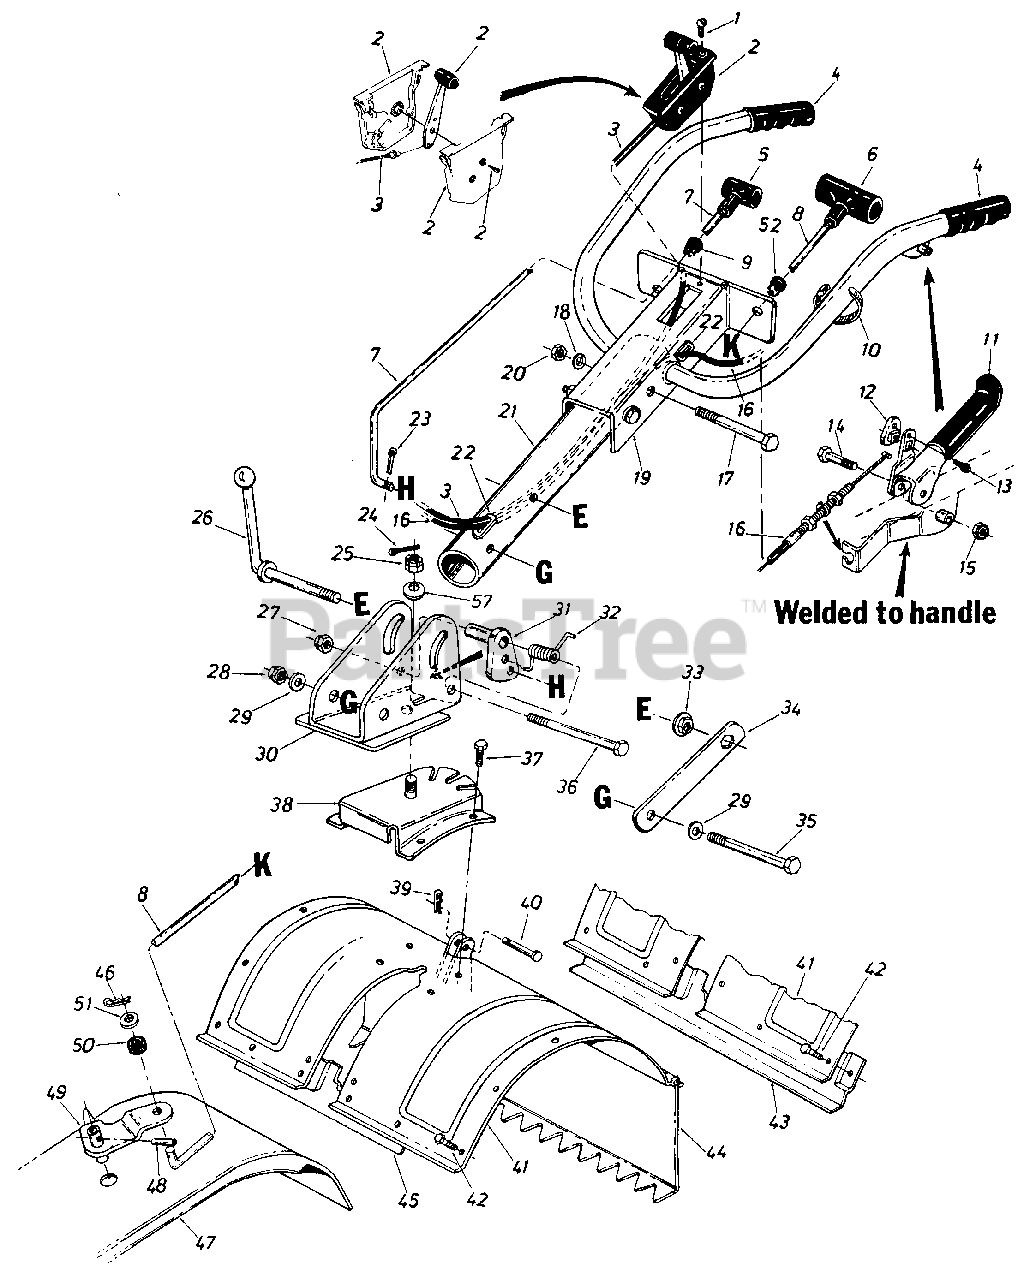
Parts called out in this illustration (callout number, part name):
1	SCREW-TRUSS TAP
2	CONTROL BOX-THROTTLE
3	CABLE-THROTTLE
4	GRIP-BLACK
5	KNOB-T
7	ROD-CLUTCH
8	ROD-CONTROL
10	TIE-CABLE
11	GRIP ASSY-LH
12	HOLD DOWN-CABLE
13	SCREW-TAP
14	SCREW-HEX 3/8-16 X 2.00
15	NUT-HEX CENTER L-JAM
16	CABLE-CLUTCH CONTROL
17	SCREW-HEX 3/8-16 X 3.00
18	WASHER-HDL 3/8
23	PIN-COTTER-3/32 DIA X .75
24	PIN-COTTER-3/32 DIA X 1.00
25	NUT-HEX SLOTTED
27	NUT-HEX CENTER L-3/8-16
28	NUT-HEX 3/8-16
29	WASHER-BELL .400 ID X .88 X .060
30	PIVOT BRKT ASSY
31	CRANK ASSY-POS
32	SPRING-HDL ADJ
33	NUT-HEX FLANGE
34	BRACKET-RETAINER
35	SCREW-HEX 3/8-16 X 3.25
36	SCREW-HEX 3/8-16 X 3.00
37	SCREW-HEX 3/8-16 X .75
38	BRACKET ASSY
39	PIN-INTERN COT
40	PIN-CLEVIS 3/8 X 1.620
43	BRACKET-REINF
46	PIN-INTERN COT-5/16 DIA
47	COVER-SHIFT
48	PIN-SPRING SPIR 3/16 X 1.00
49	CRANK ASSY-SHIFT
50	WASHER-RUBBER
51	WASHER-FL-.406 ID X 1.25 OD
57	WASHER-BELL
